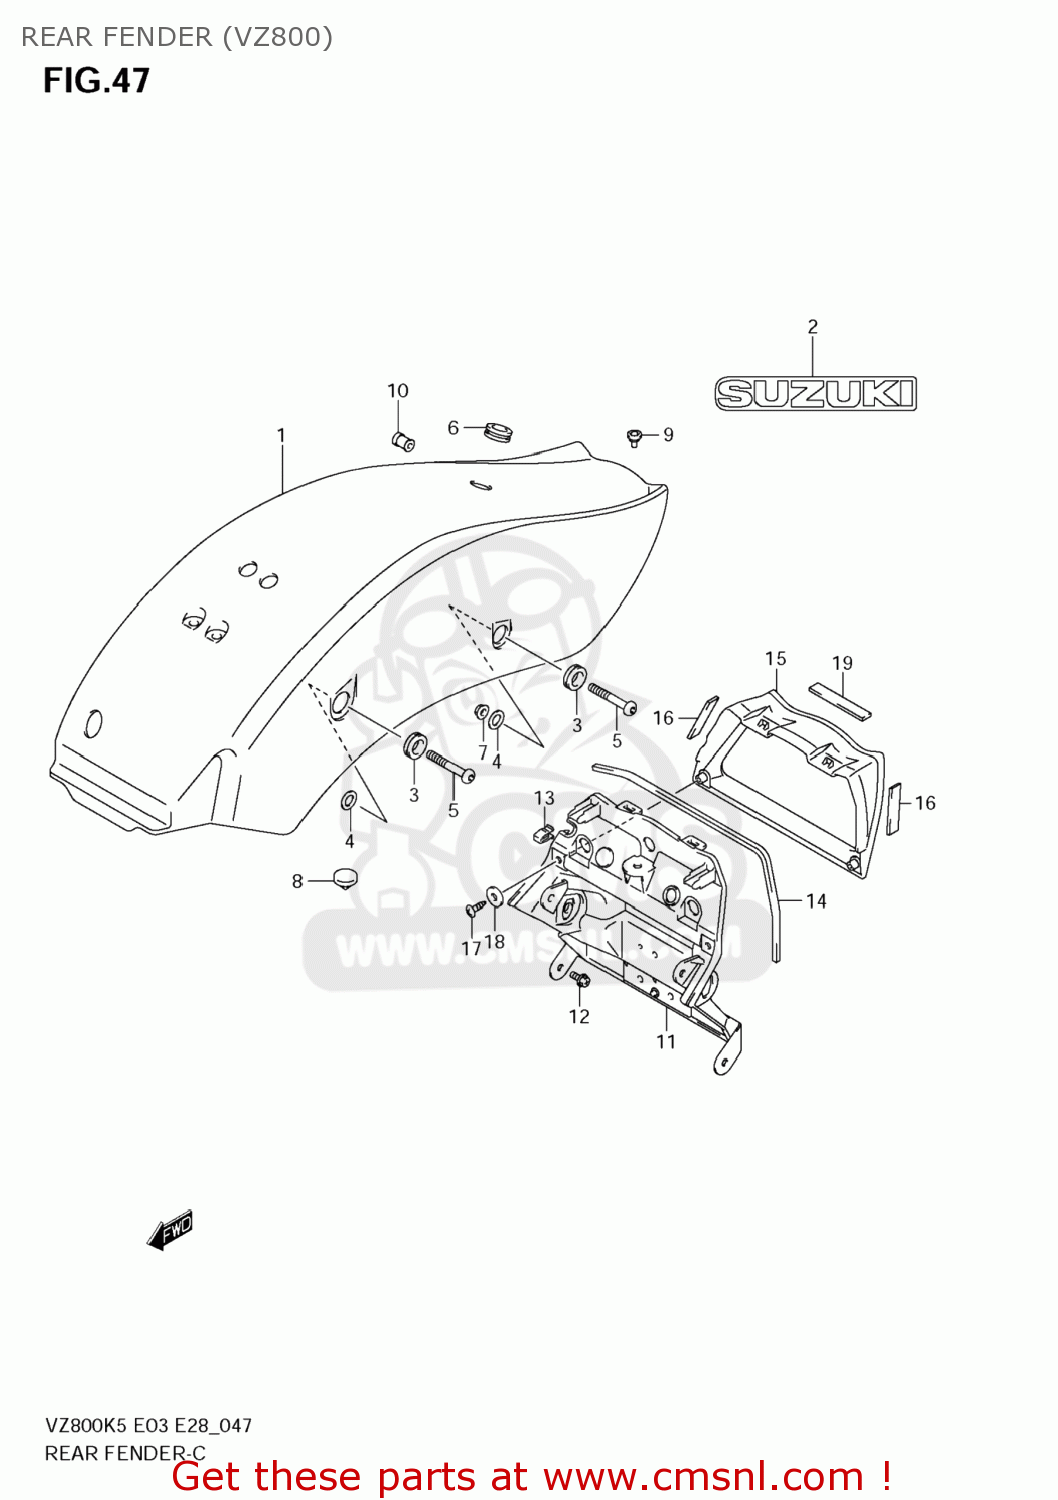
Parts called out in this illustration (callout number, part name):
1	FENDER COMP,RE
2	EMBLEM,SUZUKI
3	CUSHION,FRAME COVER UPR RR
4	WASHER(15.5X26X2.3)
5	BOLT,RR FENDER
6	CUSHION
7	NUT
8	CUSHION,RR FENDER UPR NO.1
9	CUSHION
10	CUSHION,GRIP
11	FENDER,RR RR
12	BOLT(6X16.5)
13	CLIP
14	CUSHION,RR FENDER RR
15	COVER,RR FENDER RR
16	CUSHION,RR FENDER RR COVER
17	SCREW
18	WASHER
19	CUSHION,RR FENDER RR
